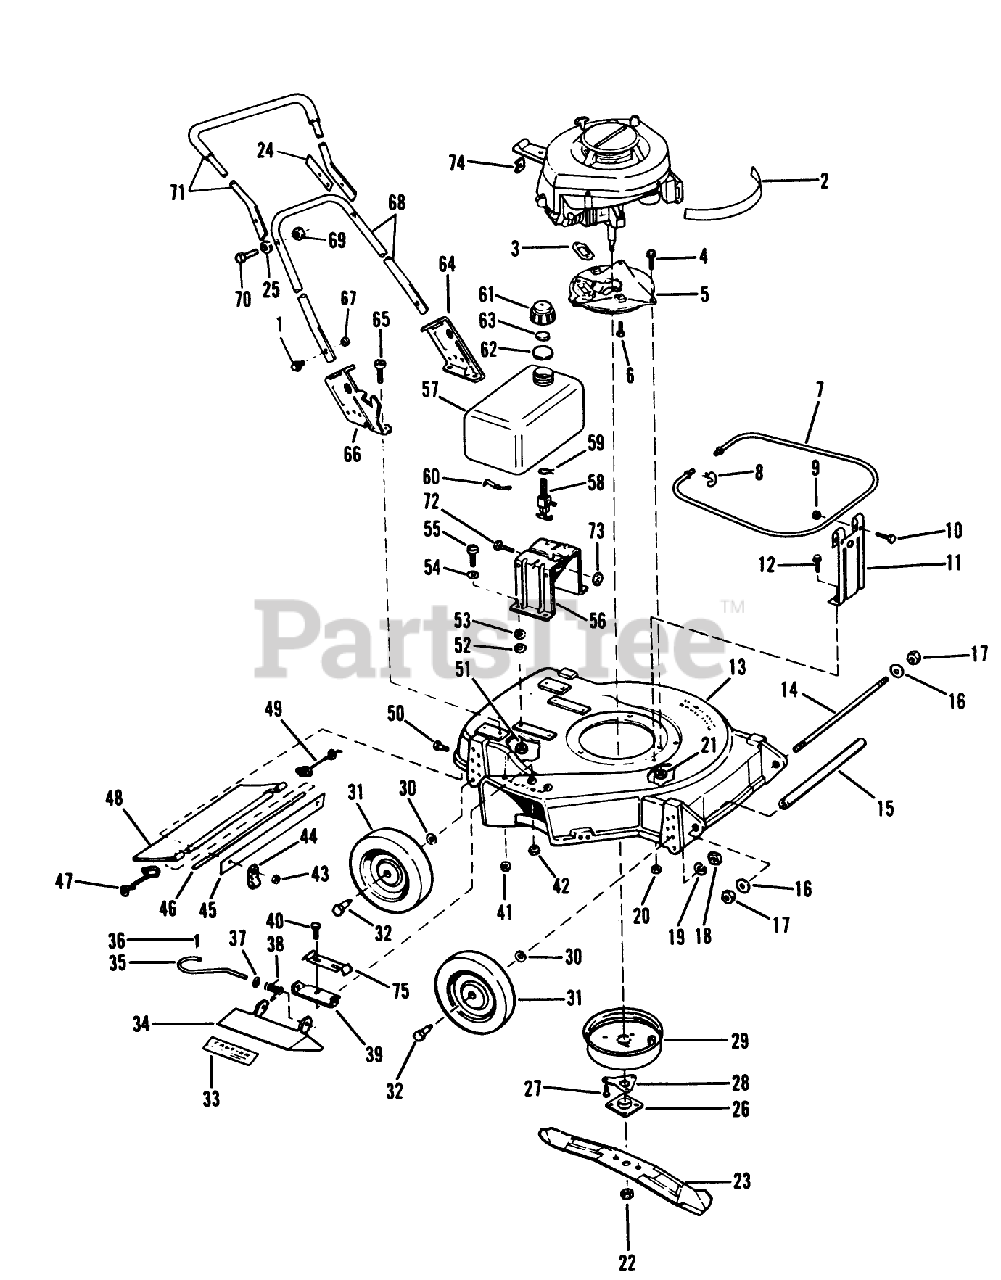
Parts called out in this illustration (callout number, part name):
1	BOLT
6	SCREW V
9	LOCKNUT E
13	HOUSING
16	WASHER WROUGHT
17	LOCKNUT
18	NUT
19	WASHER, LOCK
20	LOCKNUT E
21	NUT-LOCK F
22	NUT-BLADE
25	WASHER-CURVED
26	PLATE AND COLLAR ASM
27	SCREW
28	SUPPORT F
29	MUFFLER COVER F
30	WASHER WROUGHT
33	Decal
35	HINGE PIN
40	SCREW HEX WASHER
41	NUT-LOCK F
42	LOCKNUT E
43	LOCKNUT E
47	SPRING;TRAILING SHIELD RH
49	SPRIG T/SHLD ASOC
51	LOCKNUT E
52	WASHER
54	WASHER
55	BOLT PIONEER
58	VALVE&SCREEN SM
59	CLAMP - HOSE S
60	SPRING
62	GASKET S
63	BAFFLE - FOAM SM
67	NUT-JAM, LOCKING
68	Handle Bottom
69	LOCKNUT E
71	Top Handle Grip Assy
72	SCREW S
74	NUT-SPEED
76	WASHER-CURVED
78	BOLT
